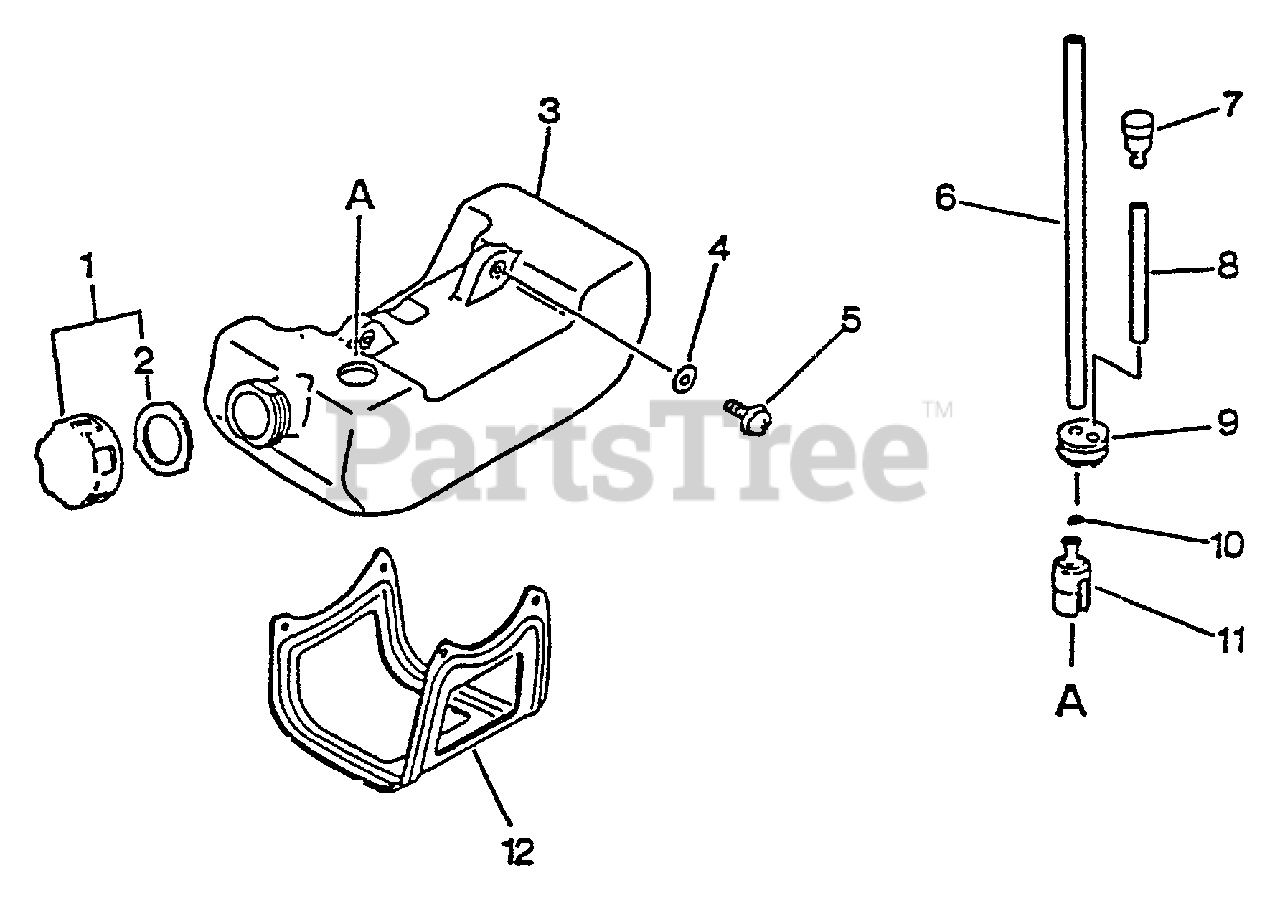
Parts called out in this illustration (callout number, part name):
1	CAP ASSY
2	GASKET, FUEL CAP
3	TANK, FUEL
4	WASHER 5.5×12×0.8
5	SCREW 5×16
6	PIPE, FUEL 3x-5x-180
7	VENT ASSY
8	PIPE, FUEL 3x-5x-70 BLACK
9	GROMMET, FUEL
10	CLIP 6 MM
11	FILTER, FUEL
12	GUARD, FUEL TANK
